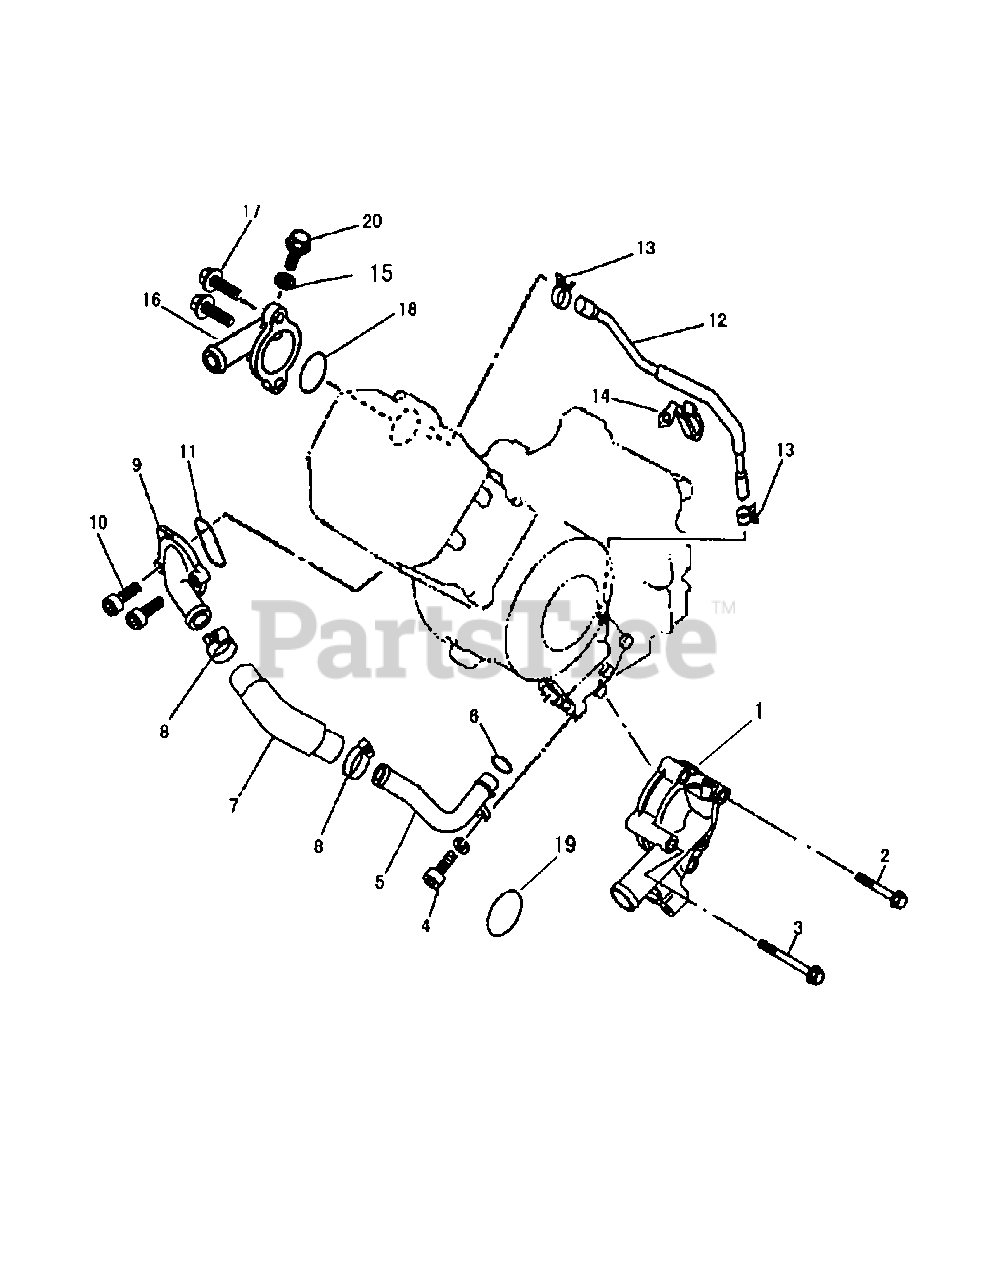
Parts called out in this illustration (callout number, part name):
1	Water Pump-Complete
2	Flangebolt M6X45
3	Flangebolt M6X65
4	Flangebolt M6X16
5	Water Pipe II
6	O-Ring 20.7X2.6
7	Water Pipe III
8	Water Pipe Clip
9	Cylinder Inlet-Water Joint
10	Flangebolt M6X20
11	O-Ring 33.4X2.4
12	Water Pipe I
15	Aluminum Washer
16	Cover-Thermostat
17	Flangebolt M6X20
18	Thermostat Cover O-Ring
19	O-Ring 34.2X2.5
20	Flangebolt M6X12
